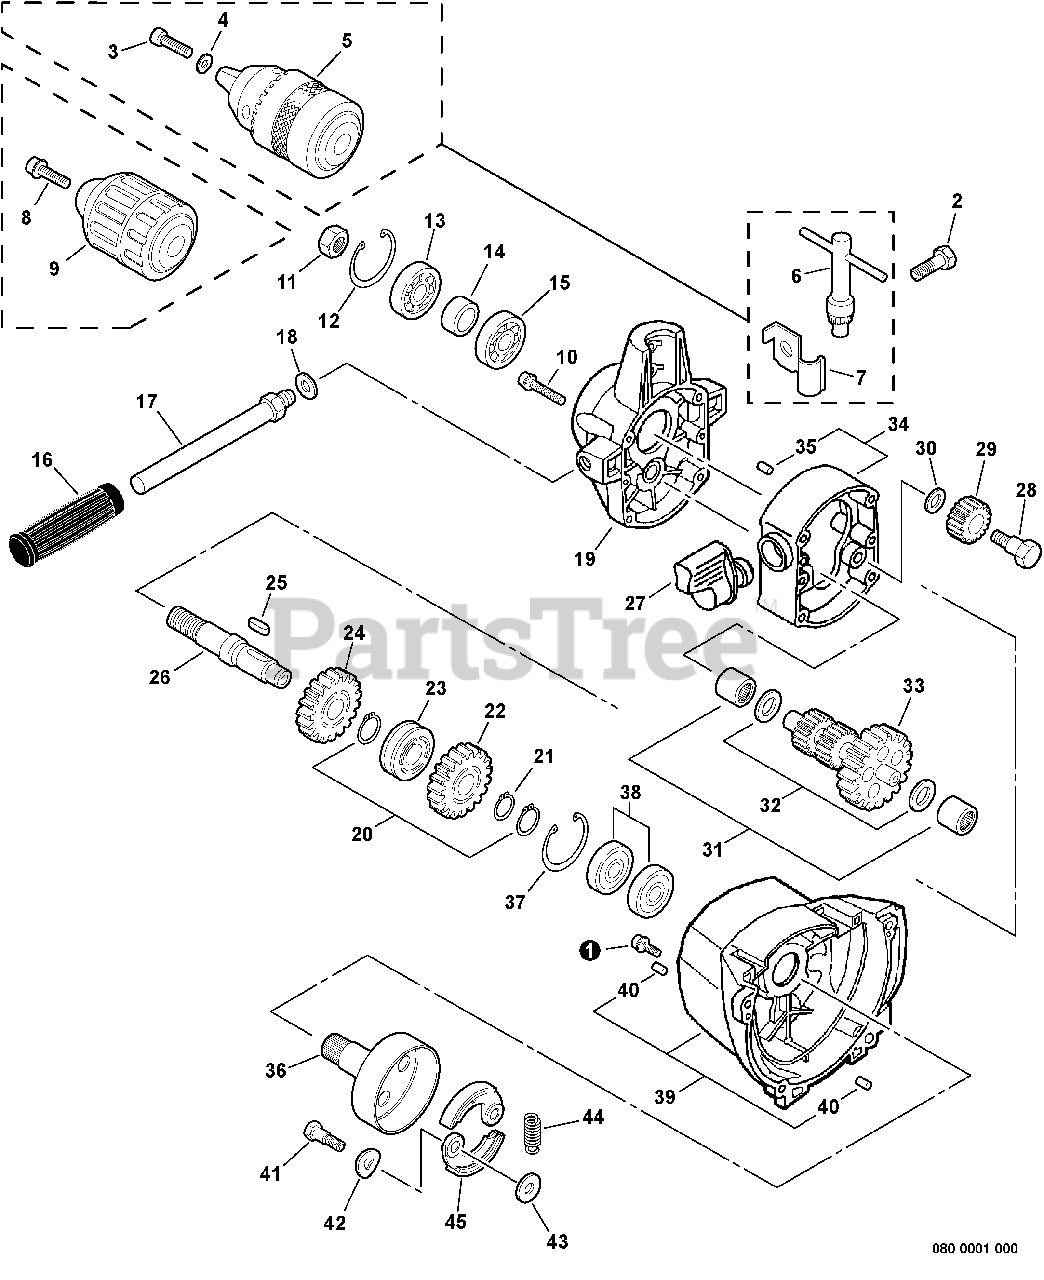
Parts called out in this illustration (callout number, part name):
1	BOLT 5×18
2	BOLT 10×1.5×15
3	BOLT 6×20
4	WASHER 6
5	CHUCK, KEYED
6	KEY, CHUCK
7	HOLDER, CHUCK KEY
8	BOLT 6×20
9	CHUCK, KEYLESS
10	BOLT 5×50
12	RING, SNAP Ø32
13	BEARING, BALL 6002 DDU
15	BEARING, BALL 6002
16	GRIP
17	HANDLE, FRONT
18	WASHER 10.5×18×1.6
19	CASE, GEAR
20	RING, RETAINING 15
21	RING, RETAINING - 12
22	GEAR, SPUR
23	CAM, CLUTCH ADJUSTER
24	GEAR, SPUR
25	KEY, WOODRUFF 4×16
26	SHAFT, AXLE
27	LEVER, CLUTCH
29	GEAR, SPUR
30	WASHER 7
31	BEARING, NEEDLE
33	GEAR ASSY
34	CASE, GEAR
35	PIN, LOCATING 4
36	DRUM, CLUTCH
37	RING, SNAP Ø32
38	BEARING, BALL 6002D
39	COVER, FAN
40	PIN, LOCATING 4
41	BOLT, CLUTCH 8×7.9×M6
42	WASHER, SPRING 8.5×16×0.5
43	WASHER 6.2×19×1.0
44	SPRING, CLUTCH
45	SHOE, CLUTCH
